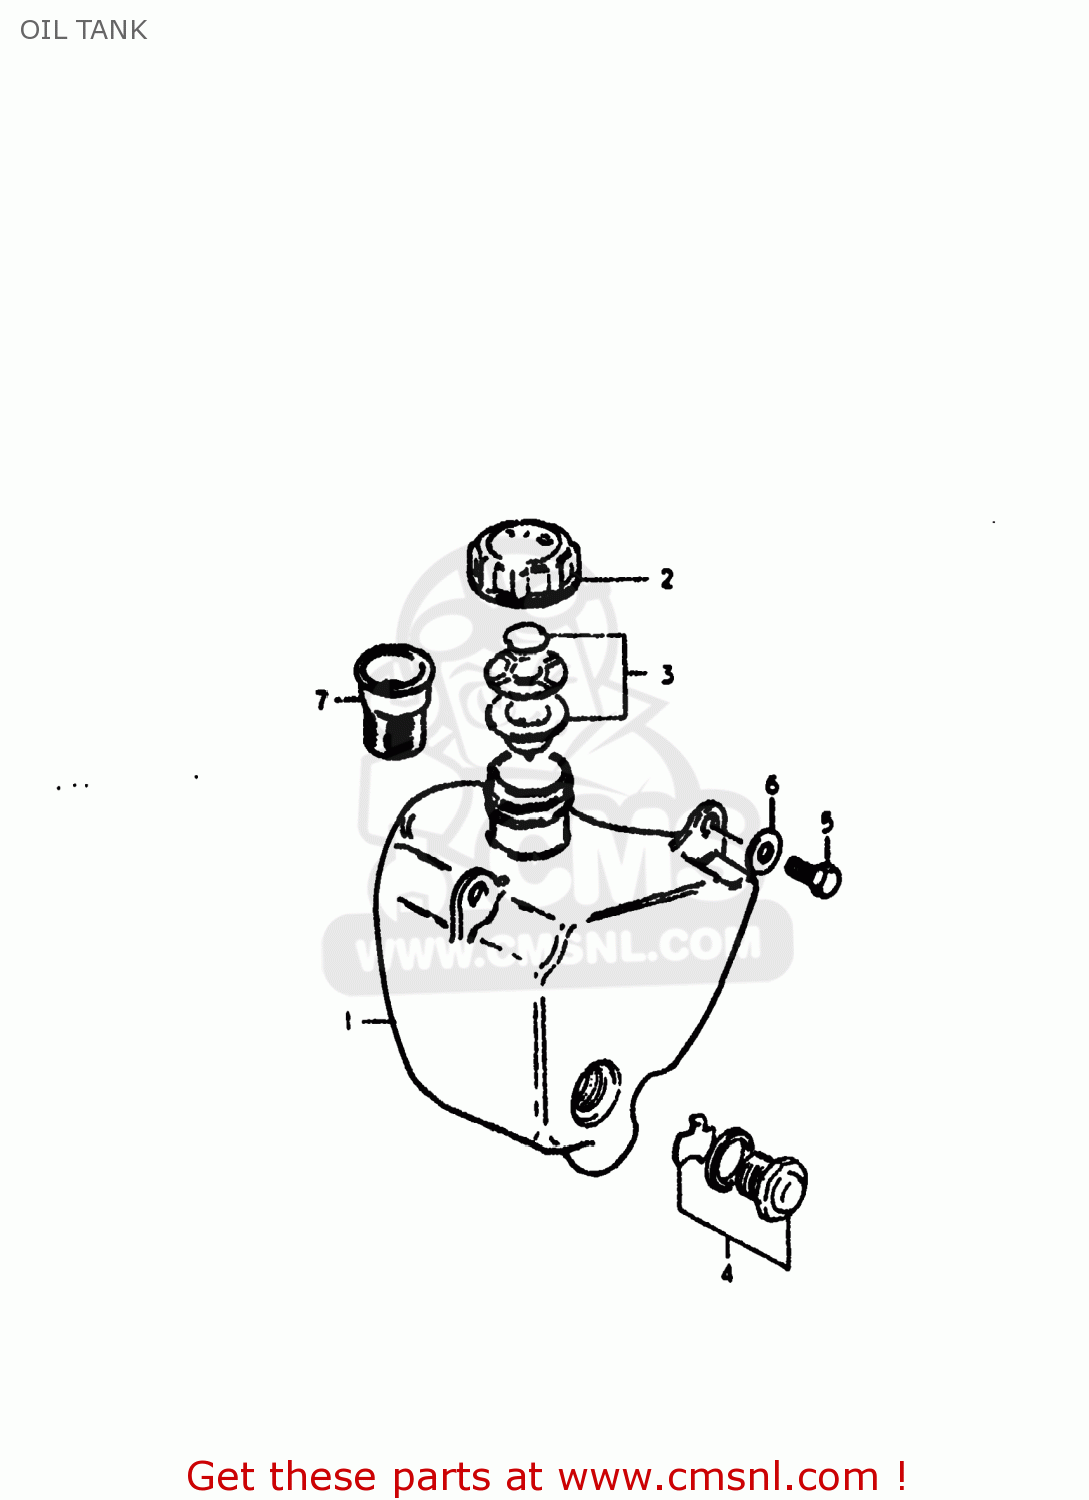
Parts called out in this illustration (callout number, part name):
1	TANK,OIL
2	CAP,OIL TANK
3	GASKET SET (NAS)
4	LENS SET,OIL LEVEL
5	BOLT, UPPER
6	WASHER
7	FILTER,OIL TANK INLET
